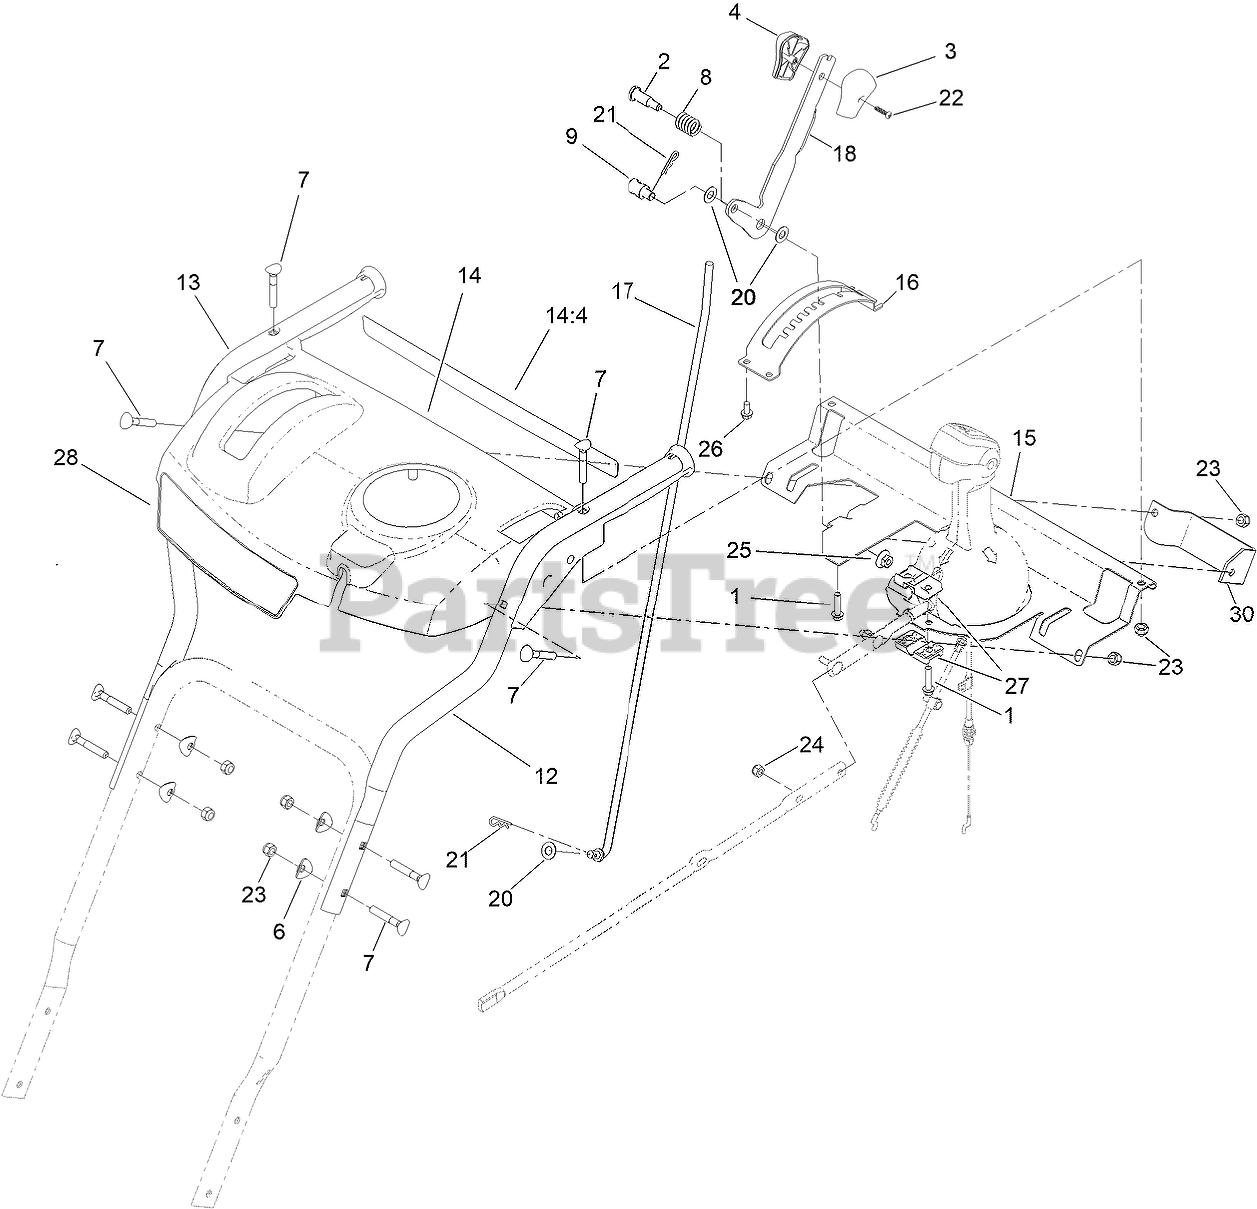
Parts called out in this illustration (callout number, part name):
1	SCREW-PLASTIC,HWH
2	SCREW-SHOULDER, HH
3	KNOB-SHIFT, LH
4	KNOB-SHIFT, RH
6	WASHER-CUP
7	SCREW-HANDLE
8	SPRING-COMPRESSION
9	TRUNNION-ROD
12	HANDLE-UPPER, LH
13	HANDLE-UPPER, RH
14	CONTROL PANEL ASM
14:4	DECAL-SAFETY
15	SUPPORT-PANEL, CONTROL
16	MOUNT-SELECTOR, SPEED
17	ROD-SELECTOR, GEAR
18	SELECTOR-SPEED
20	WASHER-THRUST
21	PIN-HAIR
22	SCREW-PPH
23	NUT-HEX
24	NUT-HEX
25	NUT-HF
26	SCREW-PLASTITE
27	SUPPORT-ROD
28	DECAL-MODEL
30	PLATE-SUPPORT, SHIFT
